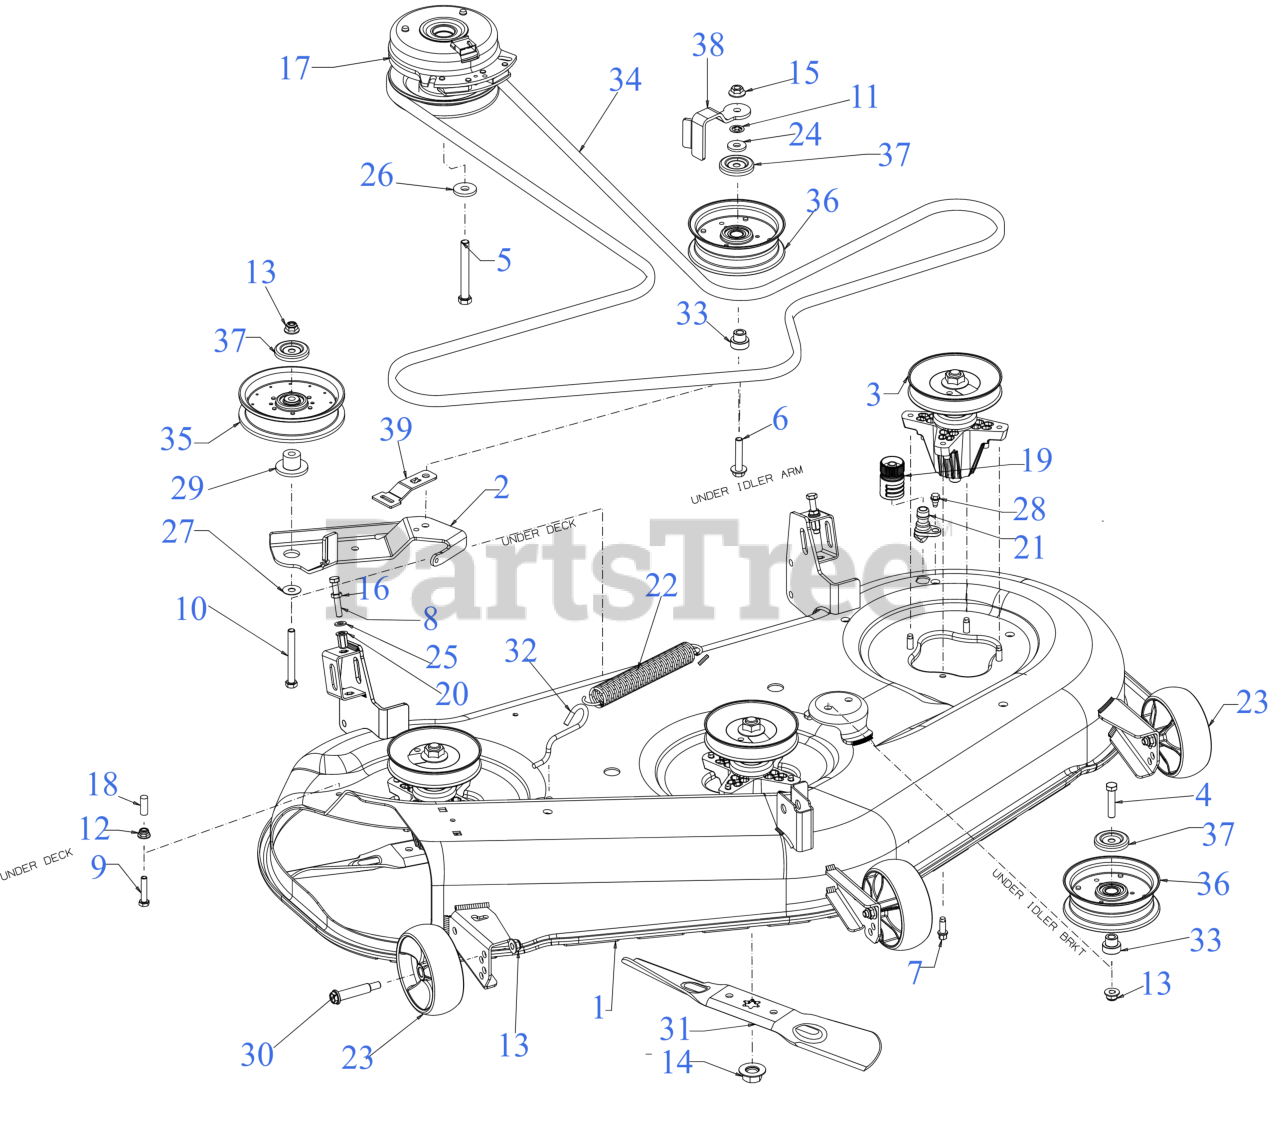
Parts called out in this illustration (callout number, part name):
1	50" DECK SHELL
2	DECK IDLER BRACKET
3	BLADE SPINDLE ASSEMBLY W/PULLEY
4	HEX SCREW 3/8-16 x 1.75 GR5
5	SCREW 7/16-20 x 3.5 GR5
6	SCREW 3/8-16 x 2.0
7	SCREW 5/16-18 x .875
8	SCREW-FULL THREAD 5/16-18 GR5
9	SCREW 5/16-18 x 1.5 LG
10	SCREW 3/8-16 x 3.25 GR8
12	FLANGE LOCK NUT 5/16-18
15	FLANGE LOCK NUT
17	ELECTRIC PTO CLUTCH
19	WATER NOZZLE ADAPTER
20	NUT RIVET 5/16-18
21	DECK WASH NOZZLE
22	EXTENSION SPRING
23	DECK WHEEL (5.0 DIA x 1.875)
24	FLAT WASHER .385 x 1.00 x .135
25	FLAT WASHER
26	FLAT WASHER .445 x 1.248 x .170
27	FLAT WASHER
28	SHOULDER SCREW 1/4-20 x .50
29	SHOULDER SPACER
30	SHOULDER BOLT (.50 X 2.0 x 3/8 -16)
31	17.27" BLADE (2N1)
31	Cub Cadet 50" HI LIFT BLADE SET
31	Genuine Factory Parts 50" BLADE SET
31	50" 6 PT STAR LOW LIFT/SAND BLADE
31	Cub Cadet 50" LOWLIFT BLADE SET
31	Genuine Factory Parts 50" LOWLIFT BLADE SET
31	50" 6 PT STAR XTREME MULCH BLADE
31	Cub Cadet 50" XTREME BLADE SET
31	Genuine Factory Parts 50" XTREME MULCH BLADE SET
32	DECK SPRING HOOK
33	SHOULDER SPACER
34	V-BELT B SEC x 143.5 LG
34	Cub Cadet 50" DECK DRIVE BELT
34	Troy-Bilt 50" DECK DRIVE BELT
35	FLAT IDLER PULLEY
36	IDLER PULLEY 4.50" DIA
37	IDLER PULLEY CAP
38	BELT KEEPER
